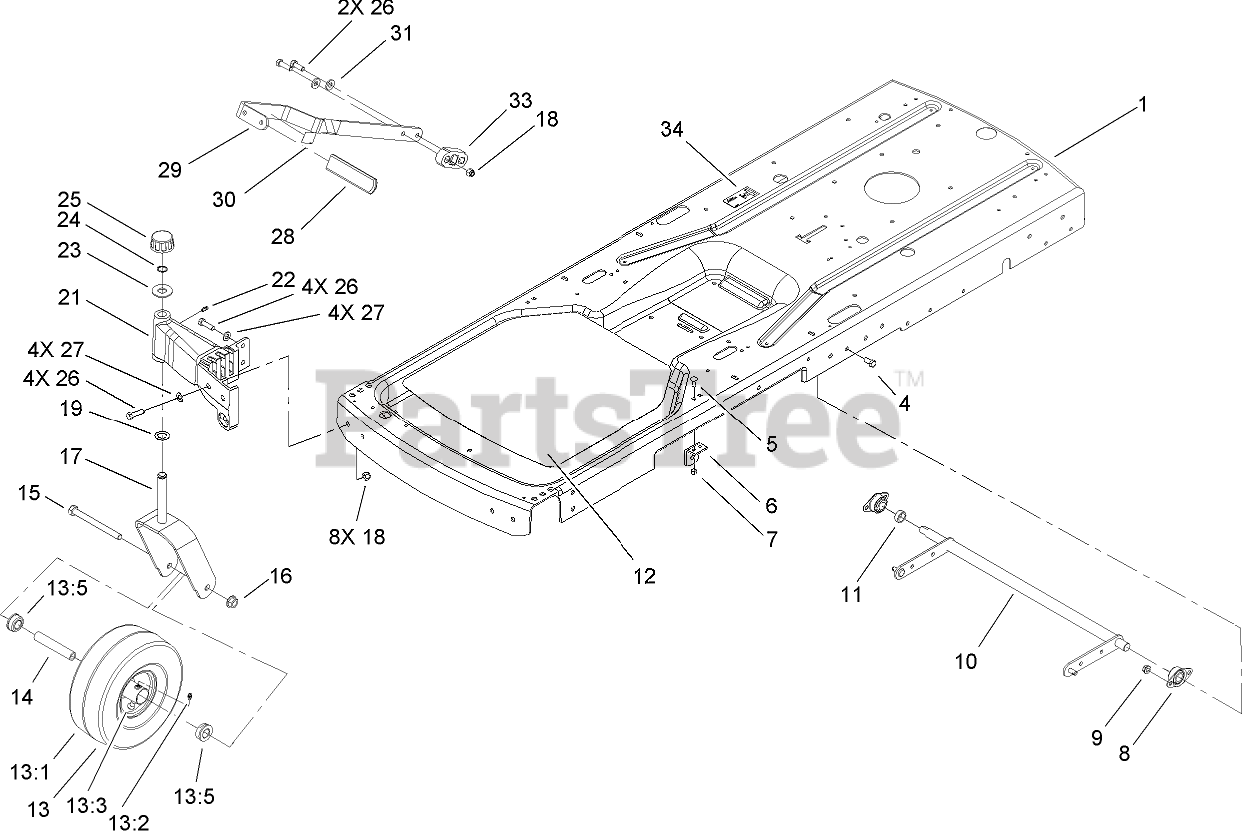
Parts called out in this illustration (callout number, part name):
4	SCREW-HH
5	BOLT-CARR
6	BRACKET-LIFT
7	NUT-LOCK, NI
8	BEARING-FLANGE, SIDE
9	NUT-HHF, WHIZ
10	LIFT ARM ASM
11	SPACER
12	PAD-ANTISKID
13	FRONT WHEEL AND TIRE ASM
13:2	FITTING-GREASE
13:3	STEM-VALVE
13:5	BUSHING-FLANGE
14	BUSHING-SPANNER
15	SCREW-HH
16	NUT-HF
17	CASTOR FORK ASM
18	NUT-LOCK, NI
19	WASHER-THRUST
21	CASTER-RH
22	FITTING-GREASE
23	WASHER-PLAIN
24	RING-RETAINING, EXT
25	CAP-HUB
26	SCREW-HH
27	WASHER-FLAT
28	GRIP-LEVER, LIFT
29	LEVER-LIFT
30	DECAL-HOC
31	WASHER-BELLEVILLE
33	BLOCK-LIFT
34	DECAL-TRANSPORT, CE
